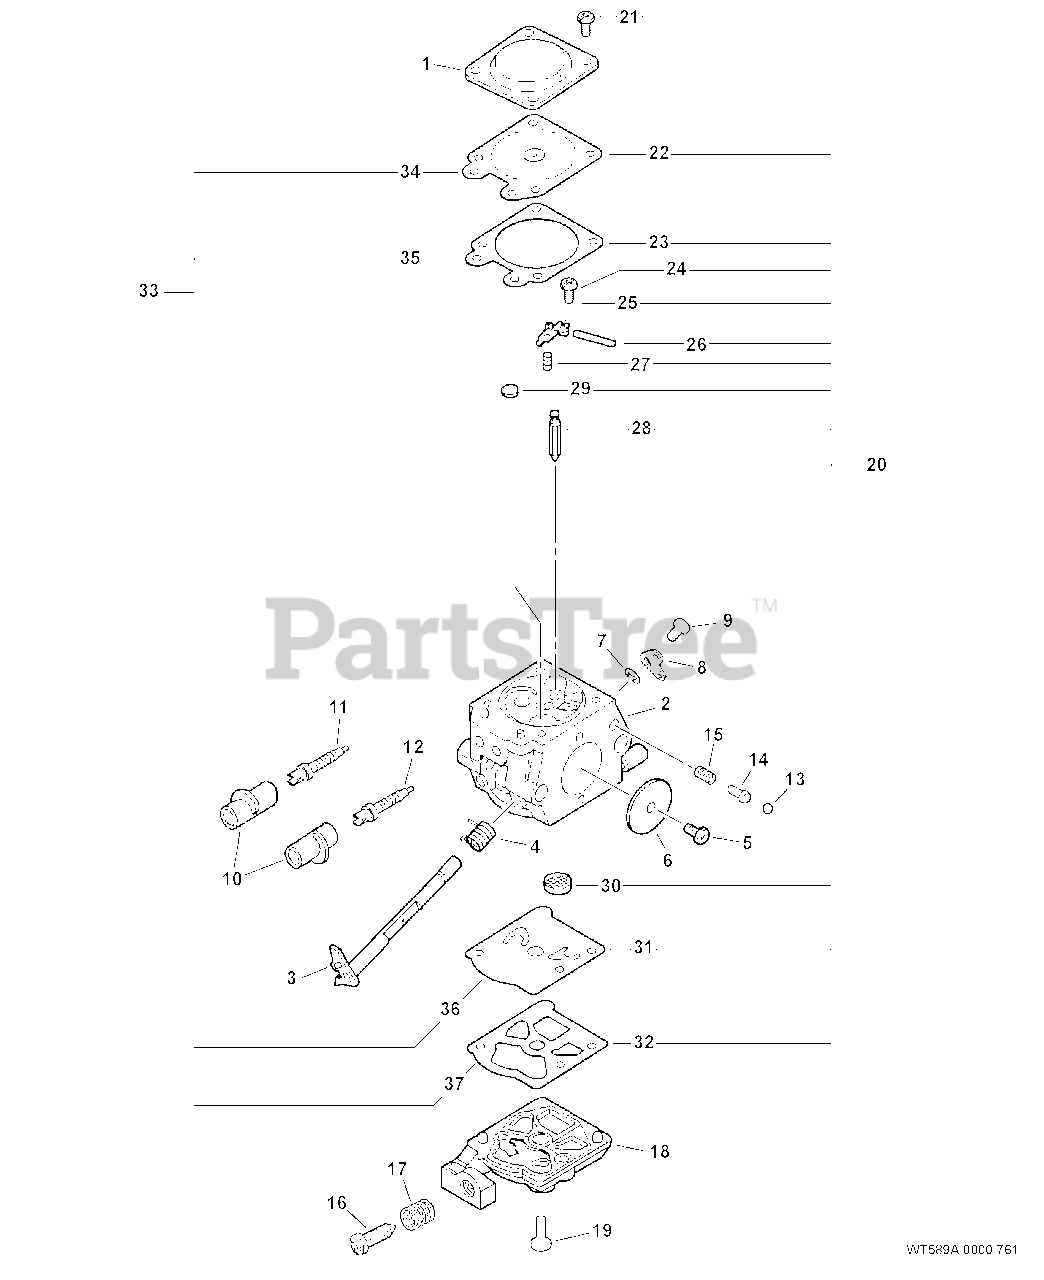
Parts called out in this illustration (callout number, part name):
1	COVER, METERING
2	BODY, CARBURETOR
3	SHAFT, THROTTLE
4	SPRING, THROTTLE RETURN
6	VALVE, THROTTLE
7	RING, RETAINING
8	LEVER, THROTTLE
10	CAP, LIMITER
11	NEEDLE - HIGH SPEED
12	NEEDLE - LOW SPEED
14	PISTON ASSY
16	SCREW, IDLE ADJUST
17	SPRING, IDLE ADJUST
18	COVER, PUMP
19	SCREW, PUMP COVER
20	REPAIR KIT
22	DIAPHRAGM, METERING
23	GASKET, DIAPHRAGM
24	SCREW, METERING LEVER PIN
25	LEVER, METERING
26	PIN, METERING LEVER
27	SPRING, METERING LEVER
28	VALVE, INLET NEEDLE
29	PLUG, WELCH
30	STRAINER
31	DIAPHRAGM, PUMP
32	GASKET, PUMP
33	DIAPHRAGM/GASKET KIT
34	DIAPHRAGM, METERING
35	GASKET, DIAPHRAGM
36	DIAPHRAGM, PUMP
37	GASKET, PUMP
